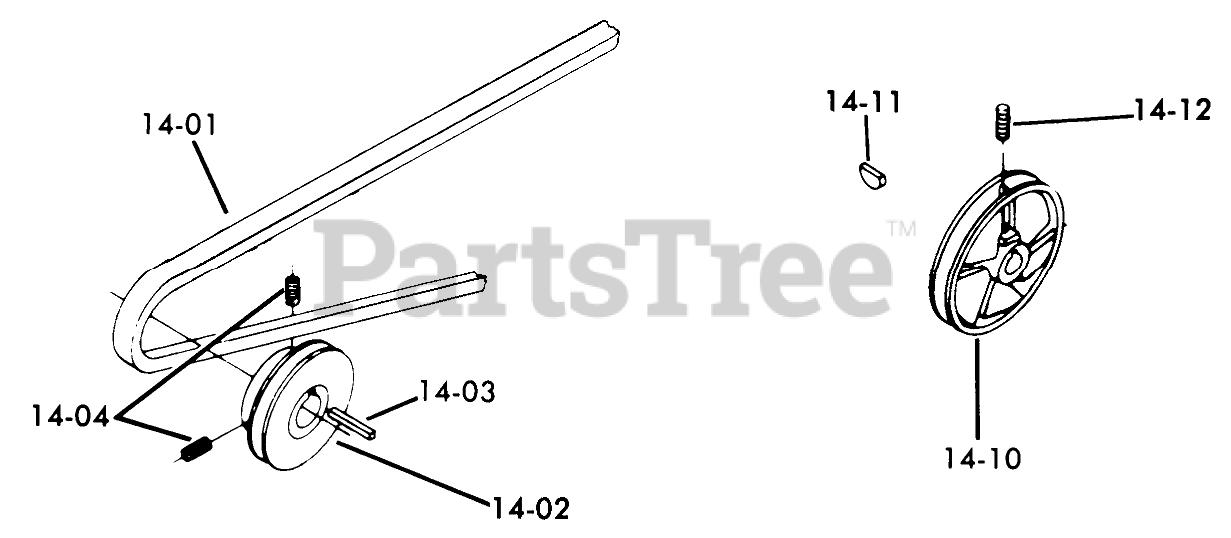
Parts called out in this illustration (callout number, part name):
14-01	V BELT
14-02	PULLEY
14-04	Set Screw
14-10	Pulley Trans
14-11	KEY-HI PRO
14-12	Set Screw
